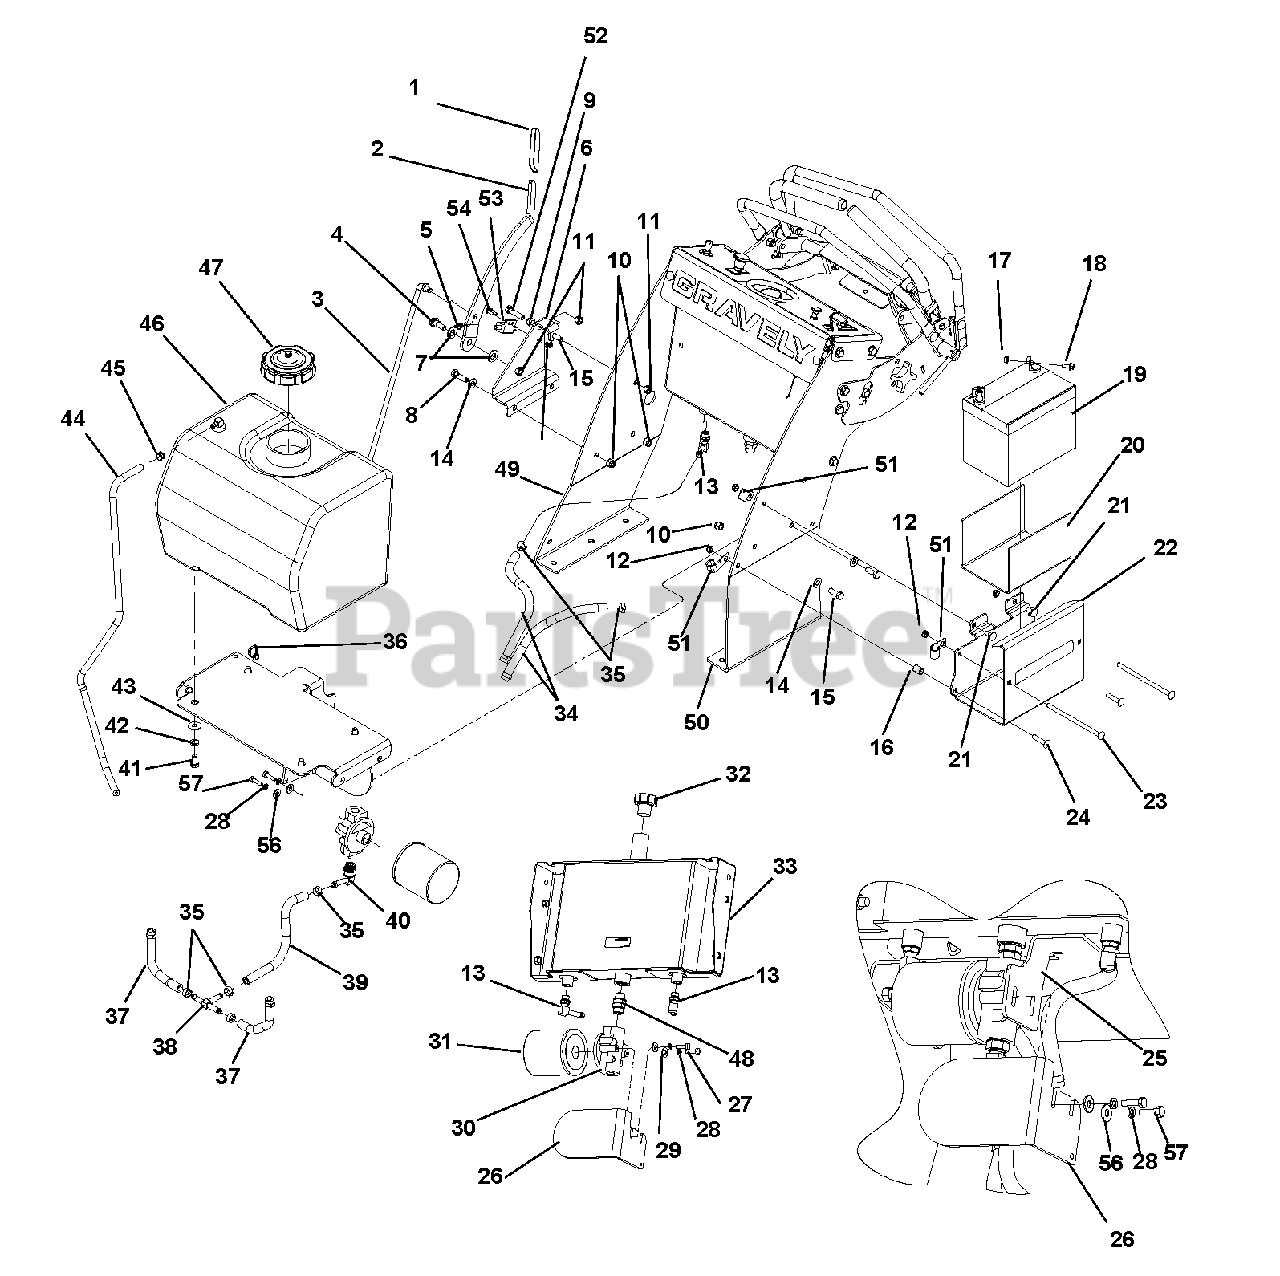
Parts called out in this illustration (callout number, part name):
1	GRIP, PVC .250 X 1.00 X 3.63
2	LEVER, HAND BRAKE FLOAT WALK
3	ROD, DRIVE CONTROL FW
4	BOLT, 1/2 X 1.06 X 3/8-16 SLD 5 Y
5	RING, RUE .375 X .054 x 1.254
6	LOCATOR, BRAKE ARM WD
7	WASHER, .510 X 1.00 X .068 NYLON
8	BOLT, .38-16 X 1.25 HEX 5 Y
9	LOCKNUT, 3/8-16 WHIZ Y
10	LOCKNUT, 3/8-16 NYLOC Y
11	LOCKNUT, 3/8-16 CENTER Y
12	LOCKNUT, 5/16-18 NYLOC Y
13	FTG, 90 9/16 MOR X 3/8 HOSE
14	WASHER, .406 X .813 X .065 FLAT Y
15	BOLT, .38-16 X 1.00 HEX 5 Y
16	BUSHING, .364X.540X.700 Y
17	LOCKNUT, 1/4-20 WHIZ Y
18	BOLT, 1/4-20 X .625 WSH Y
19	BATTERY, 12V-U1-CCA270MIN
20	STRIP, BATTERY INSULATOR
21	BOLT, RDHDSQNK .31-18 X .75 G5Y
22	TRAY, BATTERY 1948 HYDRO
23	BOLT, 5/16-18 X 6.00 CRG 2 Y
24	BOLT, RDHDSQNK .31-18 X 1.50 G5YZ
25	BRACKET, FUEL TANK RMHF
26	GUARD, HYDRO FILTER FLWLK
27	BOLT, .25-20 X 1.00 HEX 5 Y
28	WASHER, .250 MED SPRG LOCK Y
29	WASHER, .250 REG FLAT Y
30	HEAD, OIL FILTER
31	FILTER, OIL
32	CAP, OIL FILL BREATHER
33	WLDT, TANK
34	HOSE, HYD .375 X 11.5
35	CLAMP, HOSE - 1/2" PINCH
36	CABLE TIE, .15 X 8.50
37	HOSE, HYD 3/8 X 6.00
38	FTG, TUN 3/8 HOSE
39	HOSE, HYD. .375 X 12
40	FTG, 90 BRB-OR 4601-06-08
41	BOLT, .38-16 X .750 HEX 5 Y
42	WASHER, .375 MED SPRG LOCK Y
43	WASHER, .375 REG FLAT Y
44	HOSE, FUEL 1/4 X 30.00
45	CLAMP, HOSE - 1/2" SPRING
46	TANK, FUEL GRAVELY WALK REV G
47	CAP, FUEL
48	STRAIGHT UNION SAE 8
49	WLDT, RH UPRIGHT TOWER WDTL WALK
50	WLDT, LH UPRIGHT TOWER WDTL WALK
51	P-CLIP, .500 INSULATED
52	BOLT-HEX .38-16 X 1.50 GR5
53	SWITCH- DOUBLE POLE N.O./N.O.
54	SCREW, 10-24 X .625 PAN PHL
55	LOCKNUT, 10-24 NYLOC
56	WASHER, .250 REG FLAT
57	Bolt-hex .25-20 x 1.00 GR5
